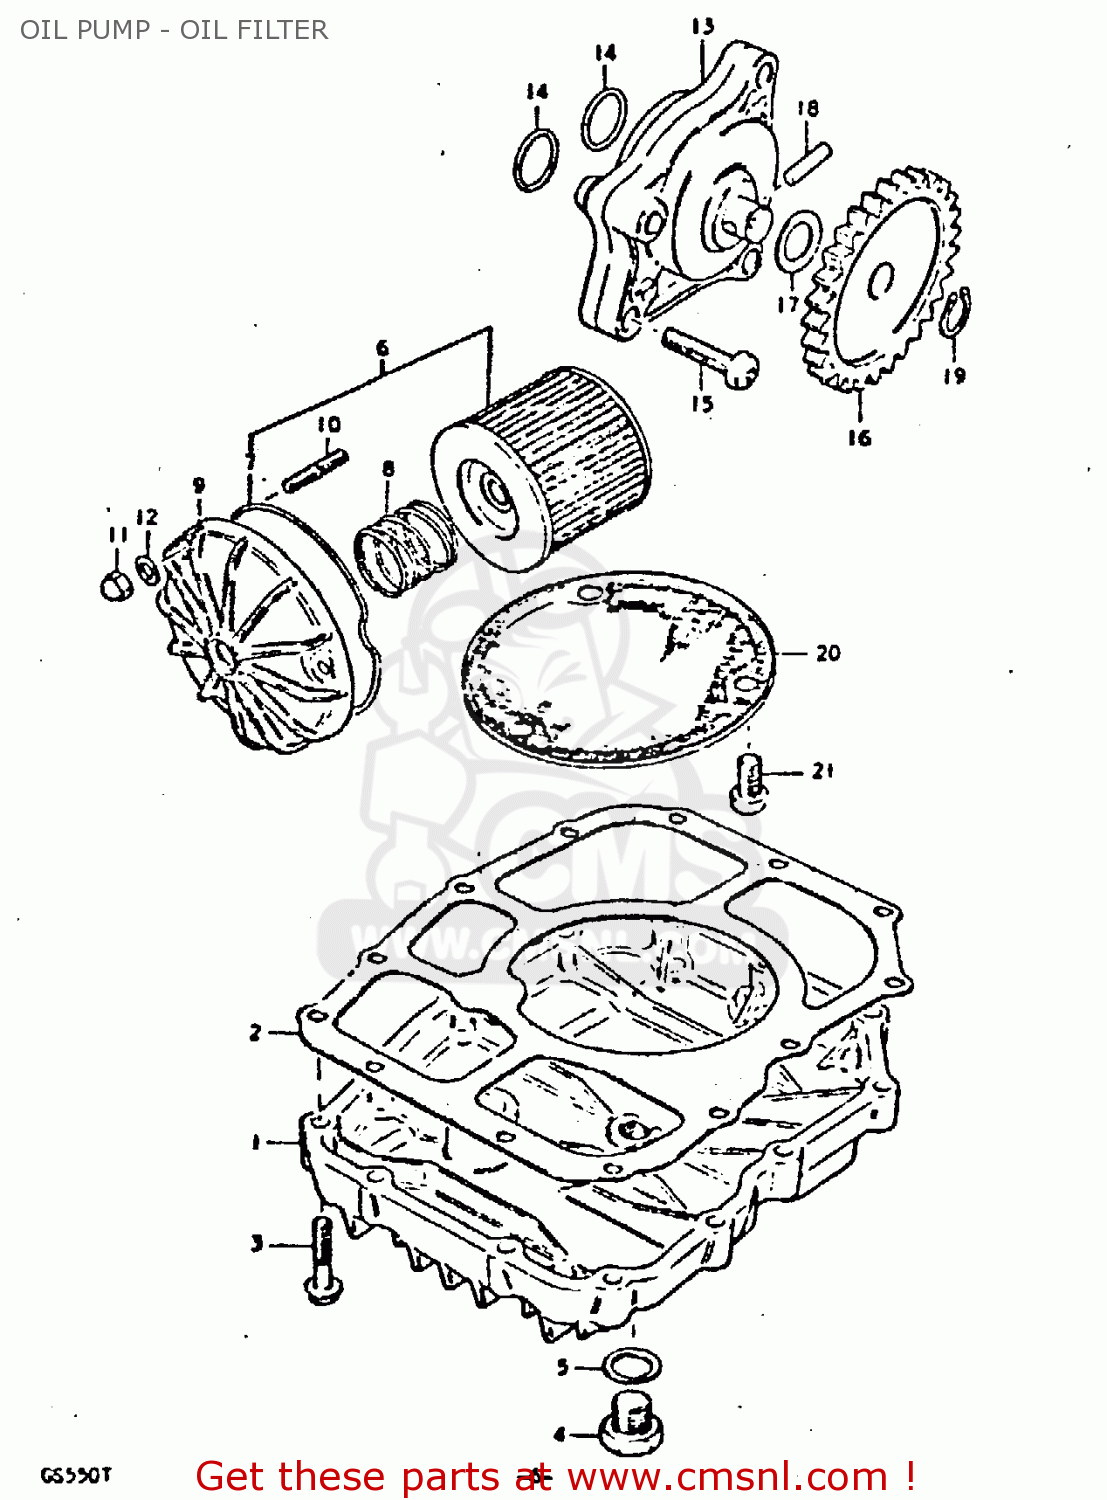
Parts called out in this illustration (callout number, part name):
1	PAN,OIL
2	GASKET,OIL PAN (MCA)
3	BOLT
4	PLUG
5	GASKET(14X19.2X2) (NAS)
6	ENGINE OIL FILTER SET
7	O RING,OIL FILTER CHAMBER CAP
8	SPRING
9	CAP,OIL FILTER
10	STUD 6X20
11	NUT
12	WASHER
13	PUMP ASSEMBLY,OIL
14	O RING(D:1.9,ID:13)
15	SCREW
16	GEAR,OIL PUMP DRIVEN
17	SHIM
18	PIN(4X15.8)
19	CIRCLIP
20	STRAINER,ENGINE OIL
21	SCREW 6X12
